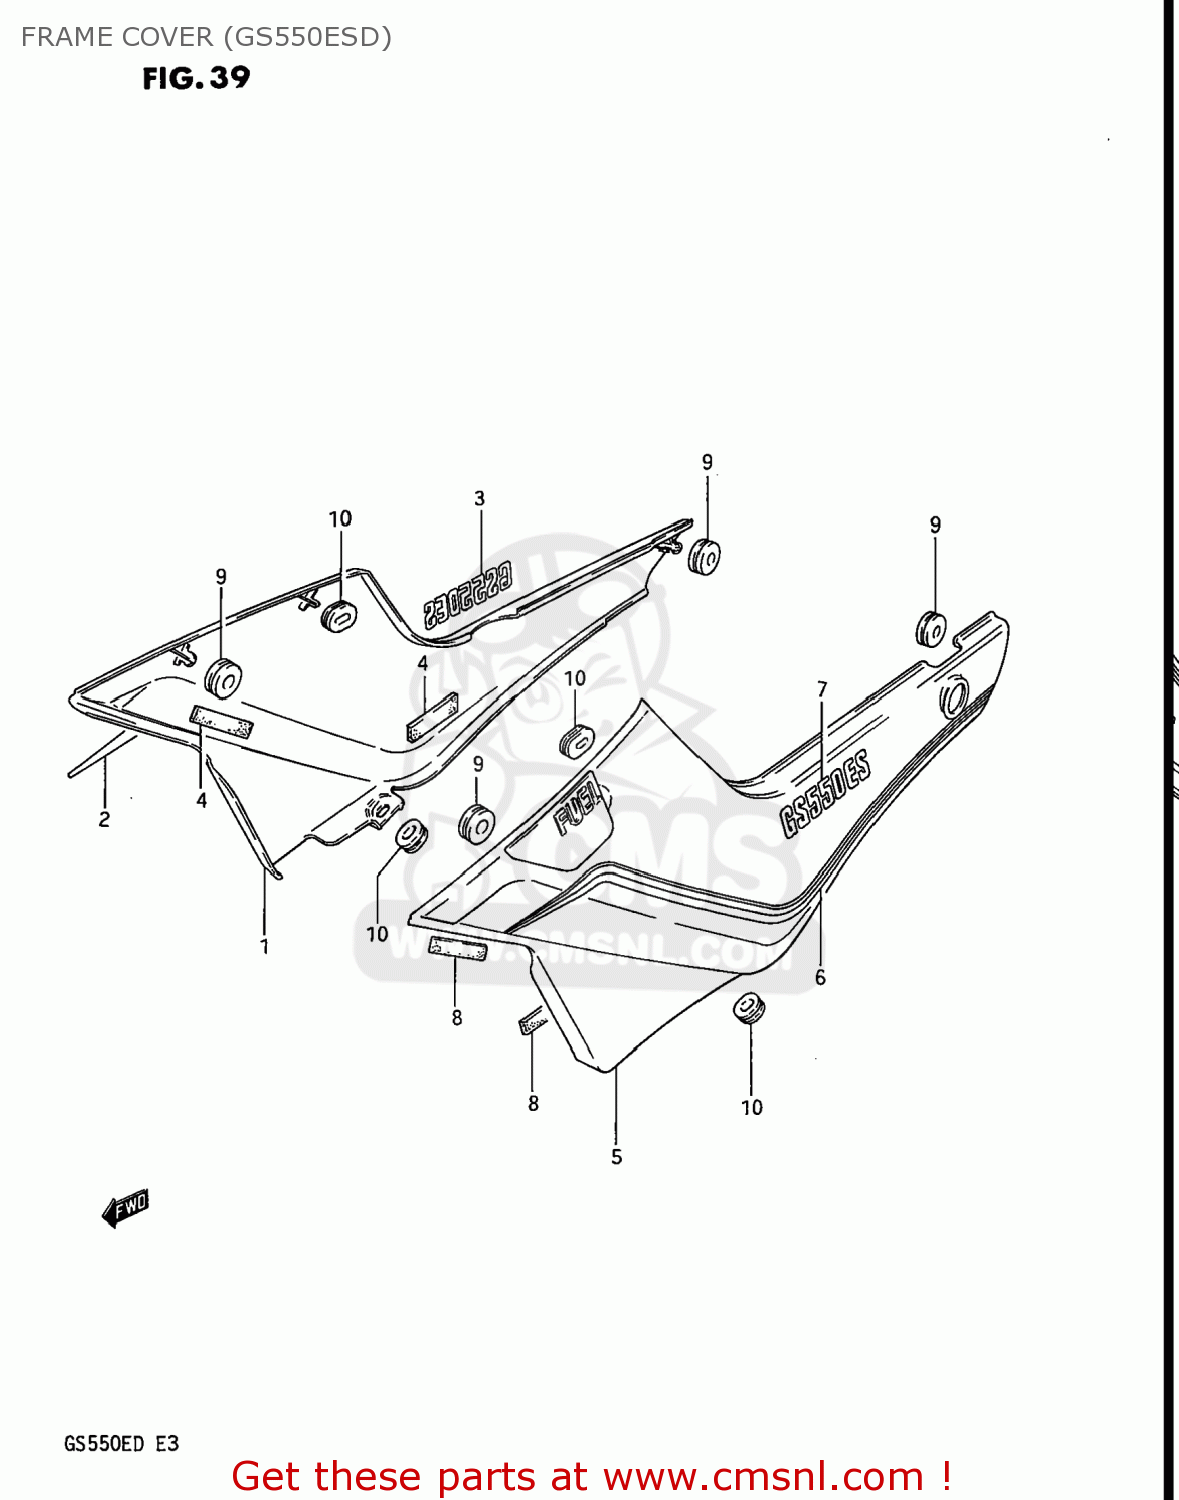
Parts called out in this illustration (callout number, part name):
1	COVER ASSEMBLY,FRAME,RIGHT
2	TAPE SET,FRAME COVER
3	EMBLEM
4	RUBBER,FRAME COVER
5	COVER ASSEMBLY,FRAME,LEFT
6	TAPE SET,FRAME COVER
7	EMBLEM
8	RUBBER,FRAME COVER
9	CUSHION
10	CUSHION
